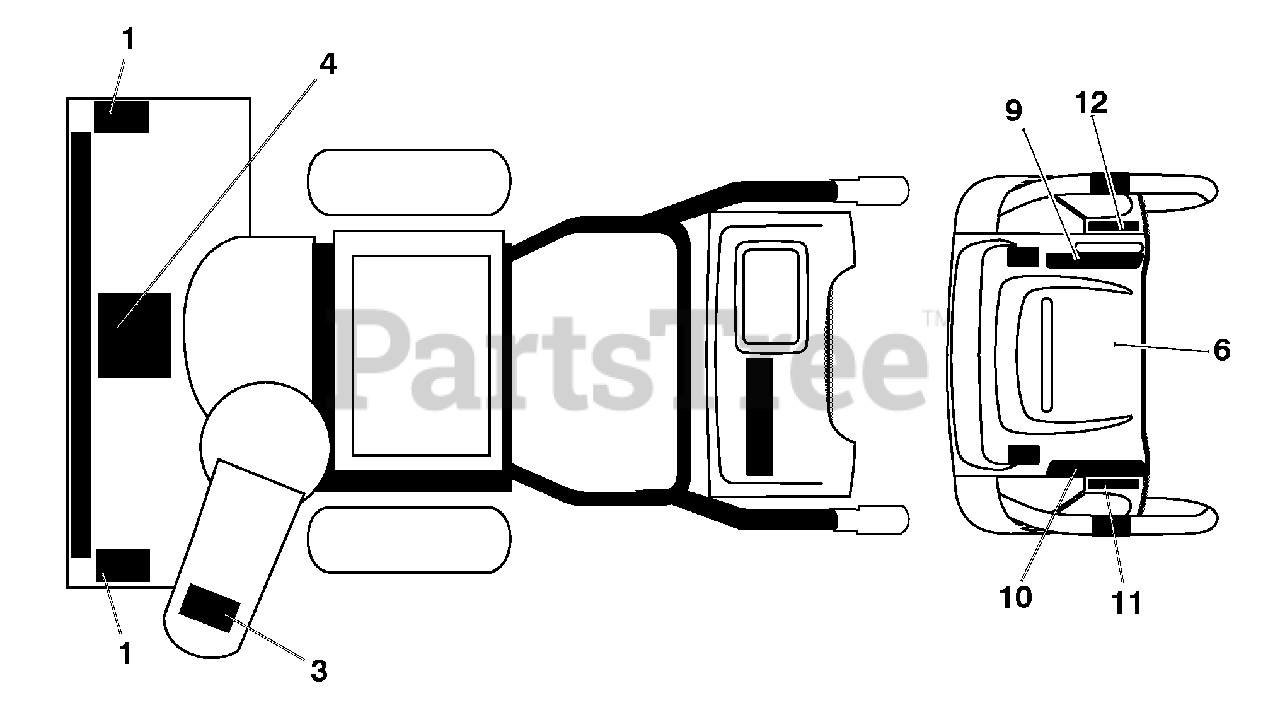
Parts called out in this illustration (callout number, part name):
1	DECAL, DANGER
3	DECAL, DANGER, DEFLECTOR
4	DECAL, DANGER
6	DECAL, INSTRUCTION
9	DECAL, SPEED CONTROL
10	DECAL, REMOTE DEFLECTOR CONTROL
11	DECAL, LH TRIGGER
12	DECAL, RH TRIGGER
12	OWNER'S MANUAL, ENGLISH
12	OWNER'S MANUAL, FRENCH
